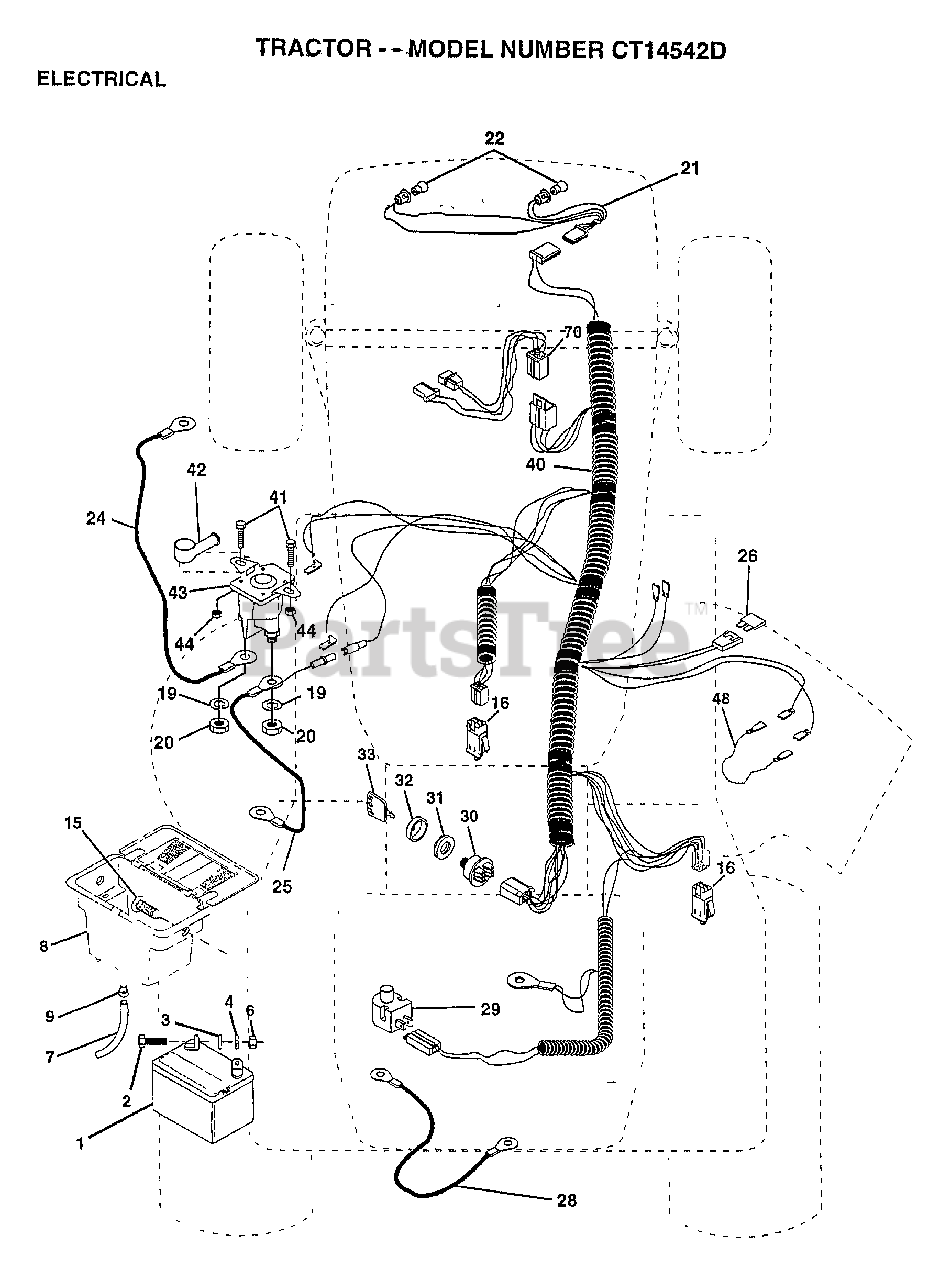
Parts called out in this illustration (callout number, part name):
2	BOLT LT
3	WASHER
4	LOCKWASHER
7	TUBE T
8	"CASE,BATTERY.MECH"
9	HOSE CLAMP T
15	FASTNER.SNAP-IN
16	SWITCH INTERLOCK
20	NUT
21	"HARNESS,LIGHT SOC"
22	HEADLAMP BULB
24	CABLE.BTRY.6GA.RD
25	CABLE.BTRY.6GA.38
26	FUSE HYT
28	CABLE T
29	SWITCH SEAT
30	SWITCH IGN 4POS
31	NUT IGNITION
32	COVER KEY SWITCH
33	KEY
40	HARNESS IGNITION
41	BOLT HXHD FIN
44	NUT HXKEP 1/4X20
48	ADAPTER AMMETER
70	HARNESS.ENG.DUAL
